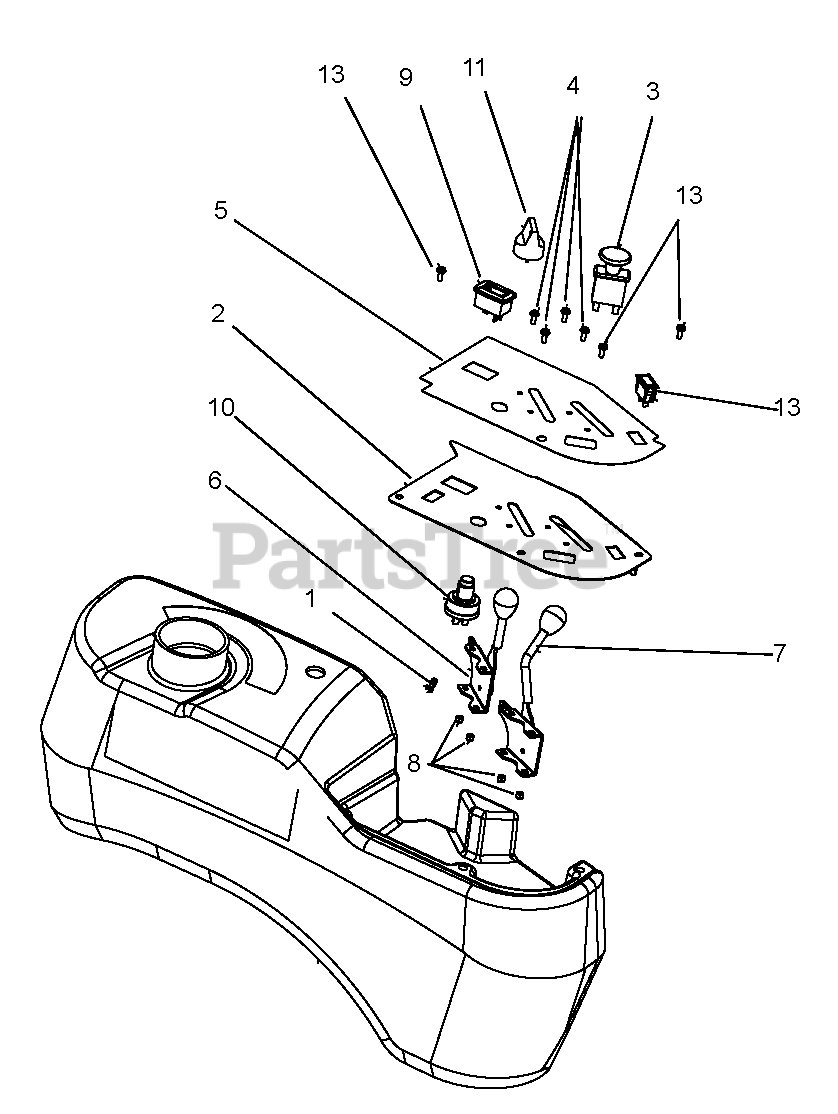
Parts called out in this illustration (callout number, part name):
1	Cable Tie w/ Tree (.25 HOLE)
2	Panel, Control
3	Switch, Clutch
4	Screw-Machine 10-24X.50 Hex Washer Head
5	Decal, Control Panel
6	Cable, Pro-Control Choke
7	Cable, Pro-Contro Throttle
8	Nut, Locking Nylon 10-24 W/INSRT YWZC
9	Meter, Hour w/Maintenance
10	Switch, Ignition
11	Key, w/ Shield
12	Light, Indicator
13	Screw, Machine 10-24 x .50 Hex Washer Head Stainless
